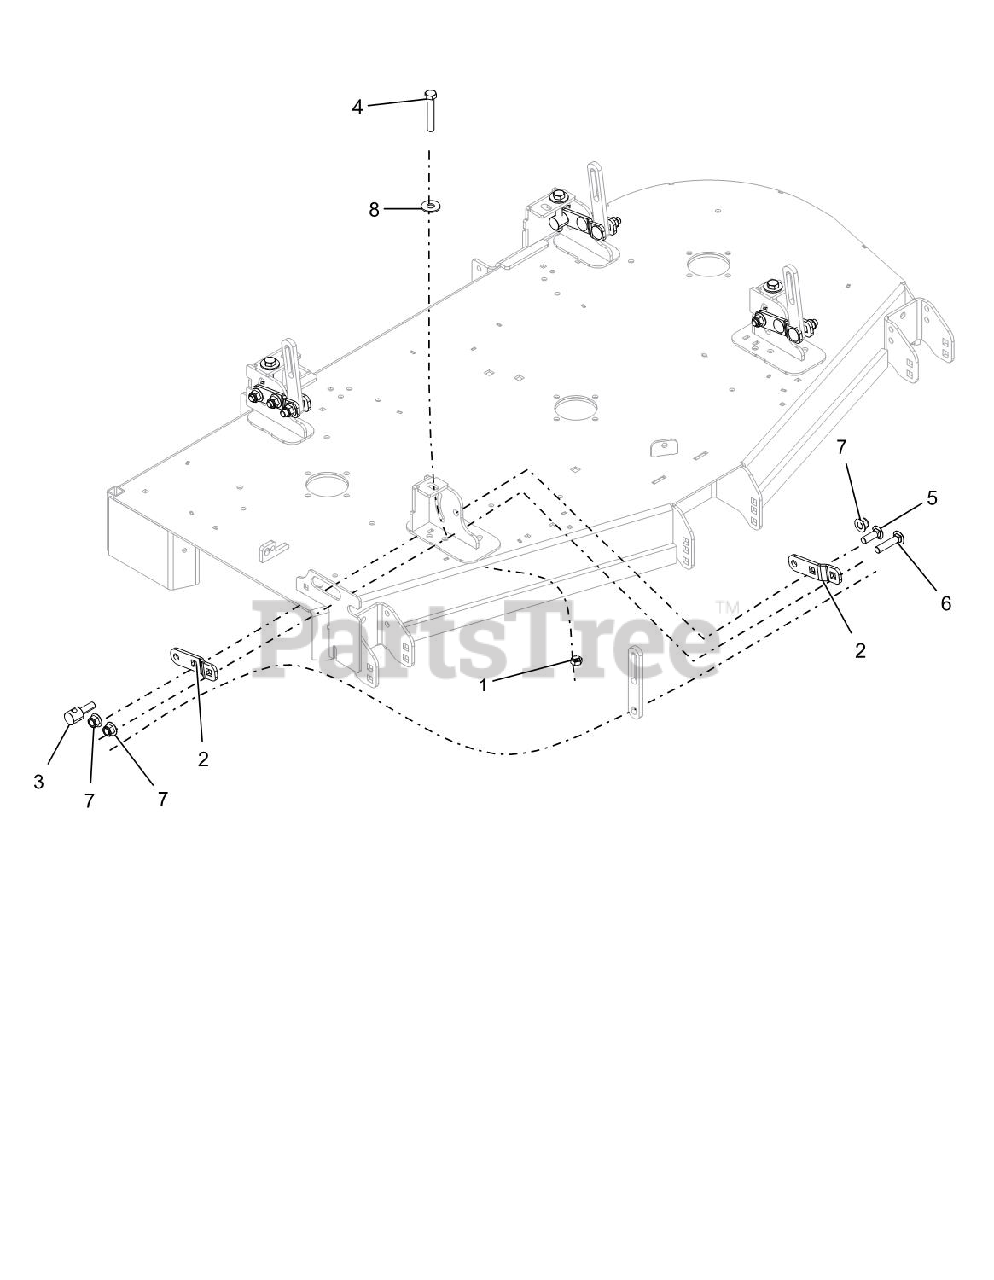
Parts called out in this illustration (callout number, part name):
1	NUT, JAM .500-13 YWZC
2	BRKT, DECK LEVELING-BLACK
3	TRUNNION, .50-13
4	BLT-HEX .50-13X3.00 GR5 FTH YWZC
5	BLT-RDHDSQNK .50-13X1.50 G5 YWZC
6	BLT-RDHDSQNK .50-13X2.25 G5 Y
7	NUT-LK-NYL-FLG .50-13 YWZC
8	WSHR-FL-STL.563X1.38X.109YWZC
